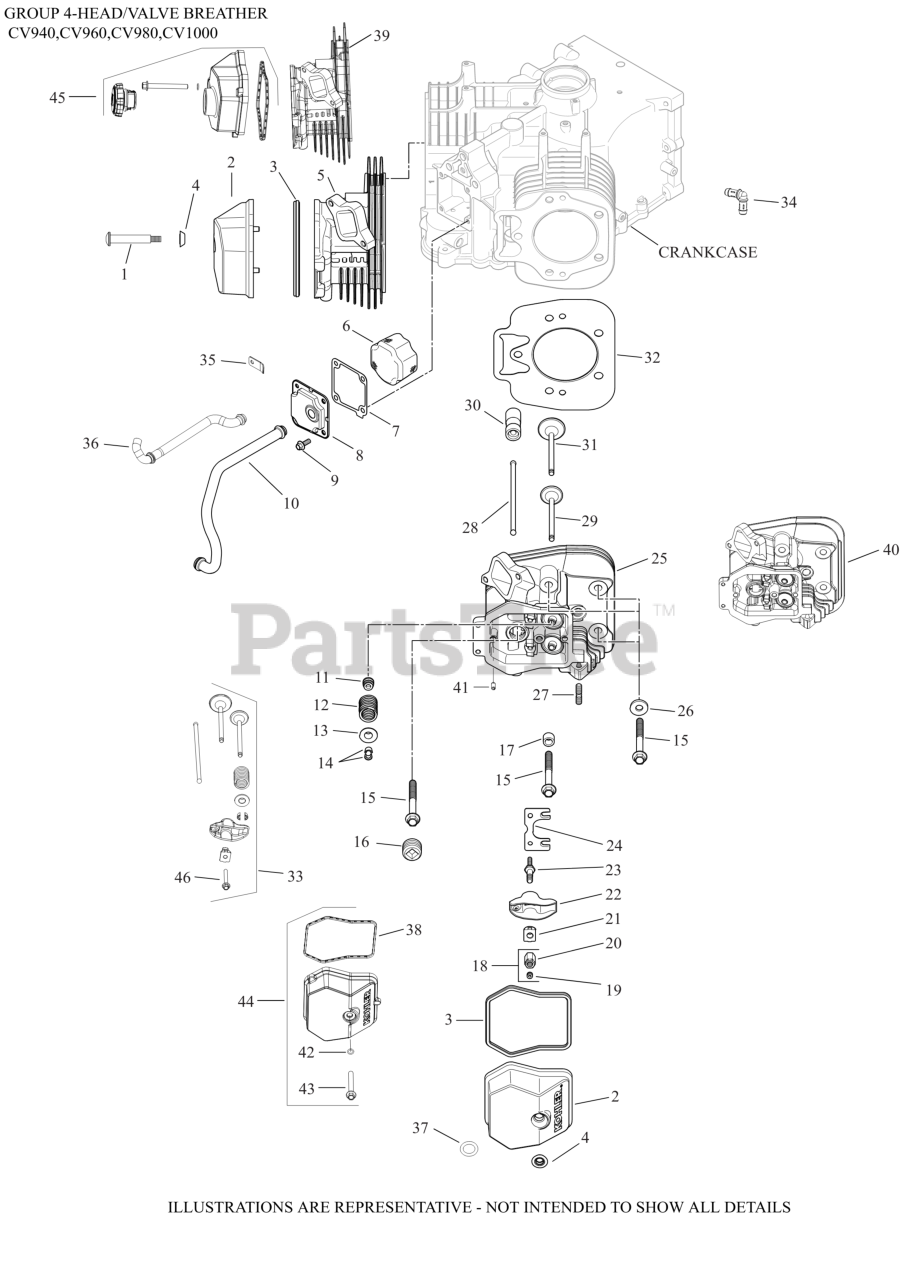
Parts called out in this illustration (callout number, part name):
1	SCREW, SHOULDER
2	KIT,COVER VALVE(NO OIL FILL)-(#6209650S)
3	SEAL, VALVE COVER
4	GROMMET, VALVE COVER SCREW
5	KIT, CYLINDER HEAD #1-USE 62 318 12-S
6	FILTER, BREATHER-USE 62 050 10-S
7	GASKET, BREATHER
8	KIT, BREATHER ASSEMBLY
9	SCREW, THREAD FORMING
9	SCREW, FLG M6X1.0X16
10	HOSE, BREATHER (VERTICAL)
11	SEAL, VALVE STEM-USE 25 032 14-S
12	SPRING, VALVE
13	CAP, VALVE SPRING
14	KIT, RETAINER
15	SCREW, FLG M10X1.5X90
16	PLUG,PIPE 3/4 NPTF SQ-USE 25 139 89-S
18	HEX NUT ASSEMBLY
19	SCREW, SET
21	PIVOT, ROCKER ARM
22	ARM, ROCKER
23	STUD, ROCKER
24	PLATE, GUIDE-DISCONTINUED
25	KIT, CYLINDER HEAD #2-USE 62 318 13-S
26	WASHER, FLAT 13/32"
28	ROD, PUSH
29	VALVE, EXHAUST
30	LIFTER, VALVE HYDRAULIC-USE 25 351 11-S
31	VALVE, INTAKE
32	KIT, CYLINDER HEAD GASKET
